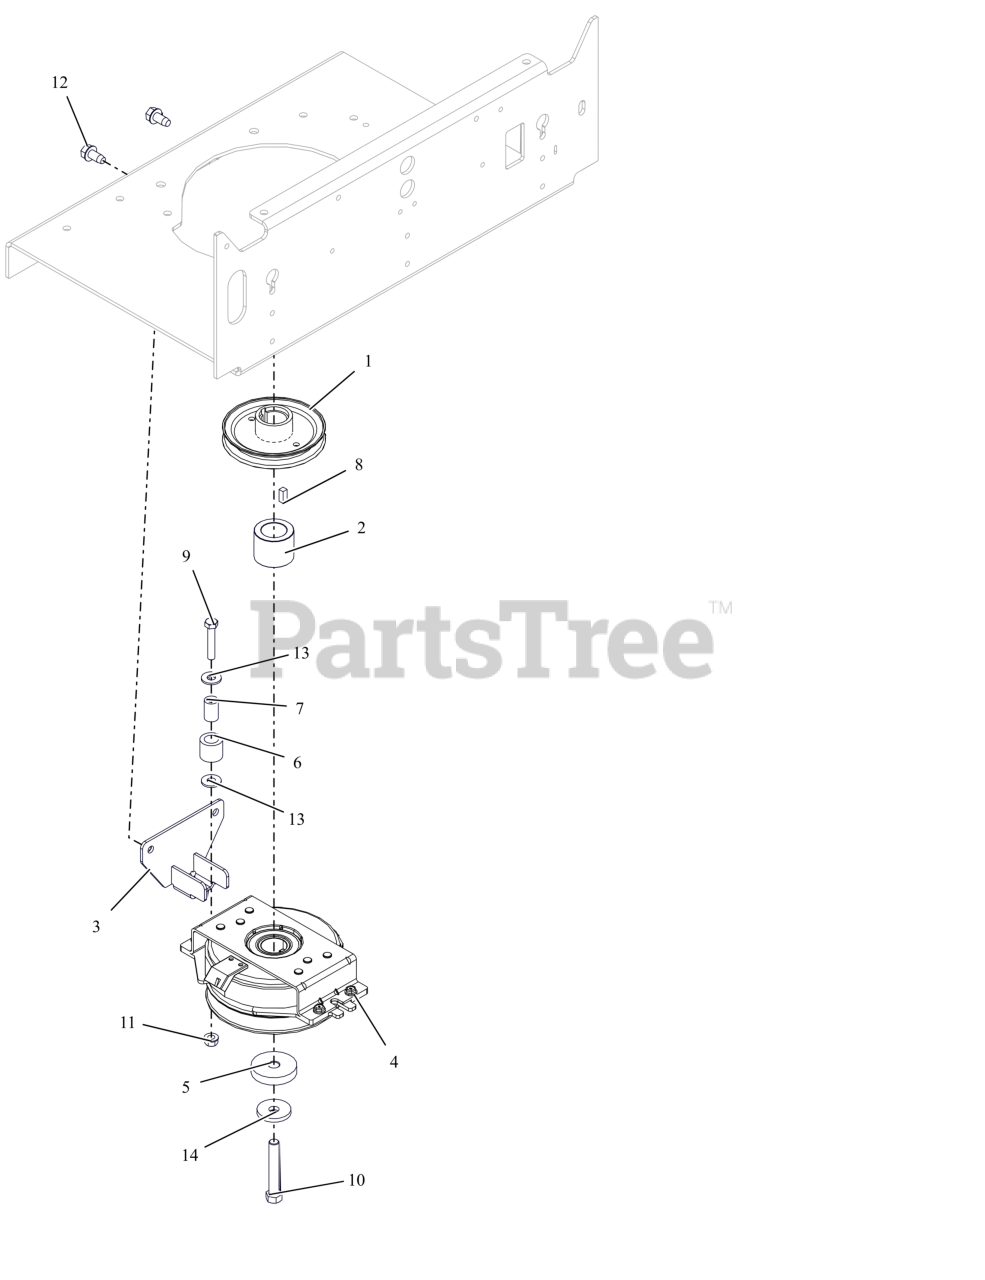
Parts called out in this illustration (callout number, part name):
1	PULLEY, 4.50 OD X 1.127 ENGINE
2	SPACER, 1.125 X 1.75 X 1.40
3	BRKT, CLUTCH STOP (BLACK)
4	CLUTCH, OGURA GT2.75-BBO1
5	SPACER, .450X2.00X.396
6	BUMPER,RUBBER .62X1.0X.88 LG
7	BUSH.,S.391X.622X.950 ST
8	KEY-SQ .25X.625X.25 SAE 8630
9	BLT, HEX .31-18X1.75 G5 ZCC
10	BLT, HEX 0.4375-20X2.75 G8 ZCC NT
11	NUT,LK-CTR-FLG .31-18 GF ZCC
12	SCR,TAP .375-16X.75 HWH TR ZCC
13	WSHR,FLT .375X.875X.083 ZCC
14	WASHER, 7/16" SPRING DISK
